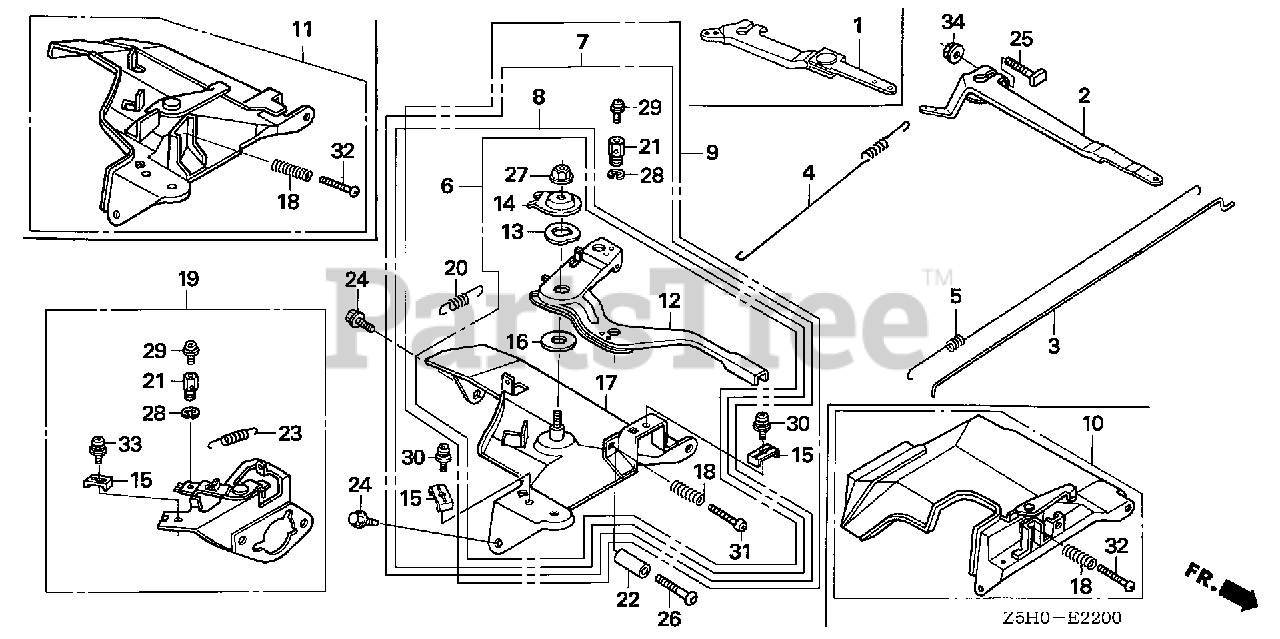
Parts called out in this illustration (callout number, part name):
2	ARM, GOVERNOR
3	ROD, GOVERNOR
4	SPRING, GOVERNOR (L=145.0MM) (WIRE DIAMETER 1.0MM)
4	SPRING, GOVERNOR (L=142.0MM)
5	SPRING, THROTTLE RETURN
10	CONTROL ASSY.
18	SPRING, CONTROL ADJUSTING
22	COLLAR, STOPPER
24	BOLT, FLANGE (6X12) (CT200)
25	BOLT, GOVERNOR ARM
26	SCREW, RECESSED (5X25)
32	SCREW, PAN (5X35)
34	NUT, FLANGE (6MM)
